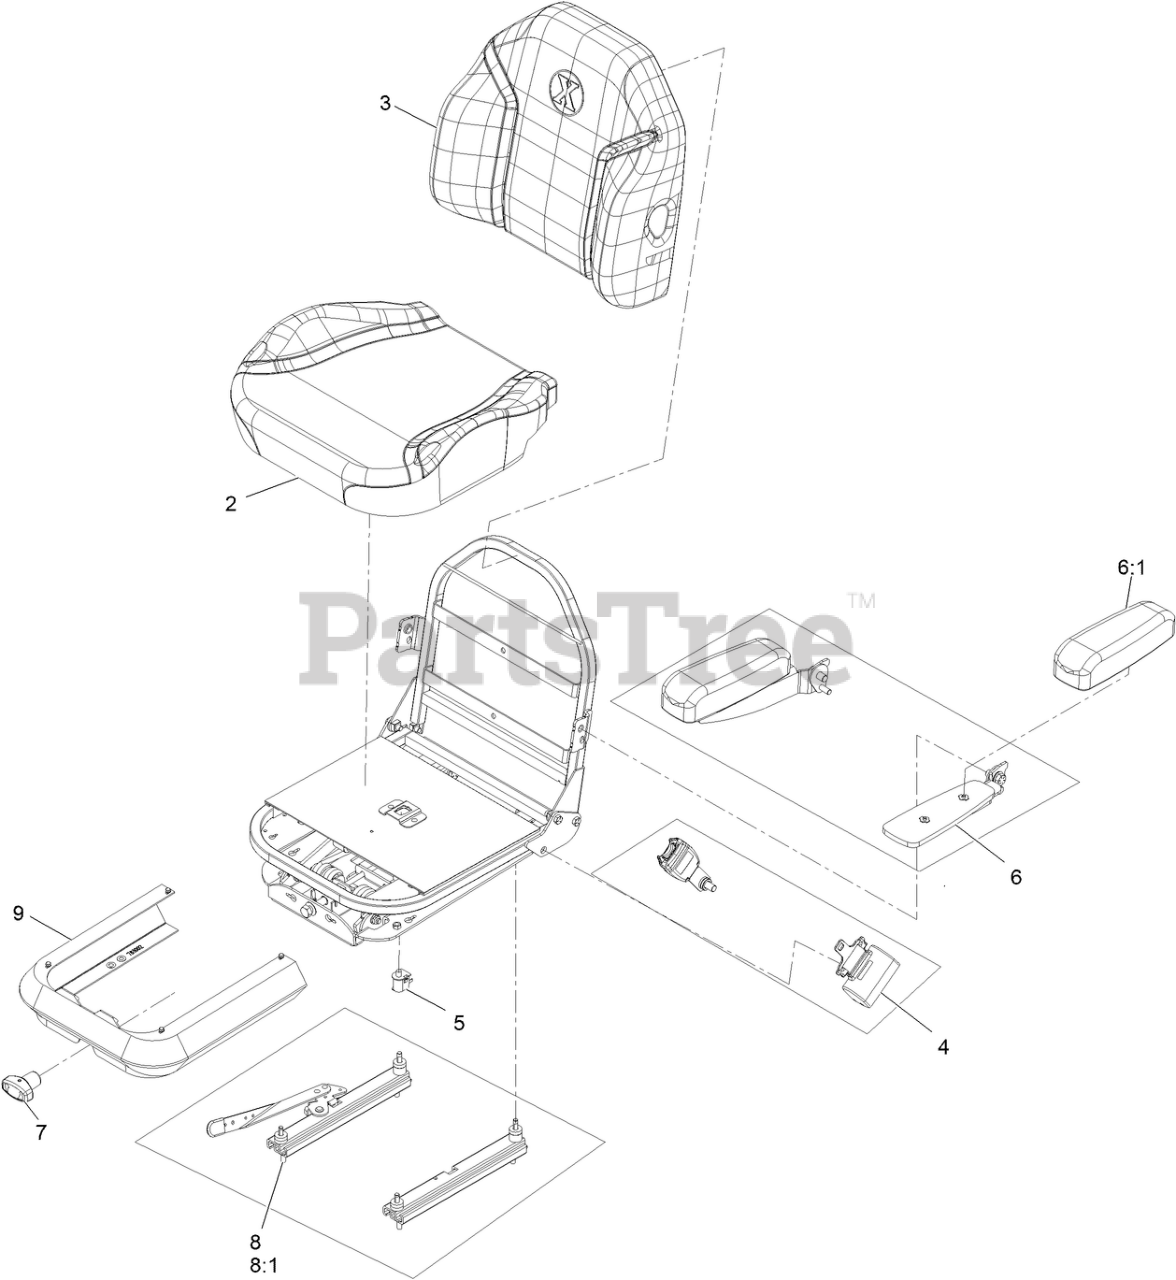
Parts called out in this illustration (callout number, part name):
2	Cover, Lower
3	Cover, Upper
4	Seat Belt Kit
5	SWITCH-BAIL
6	KIT-ARM REST
6:1	CUSHION-ARM REST
7	KNOB-ADJUSTER
8	KIT-TRACK-SEAT 4""
9	Cover-Skirt W/Fasteners
